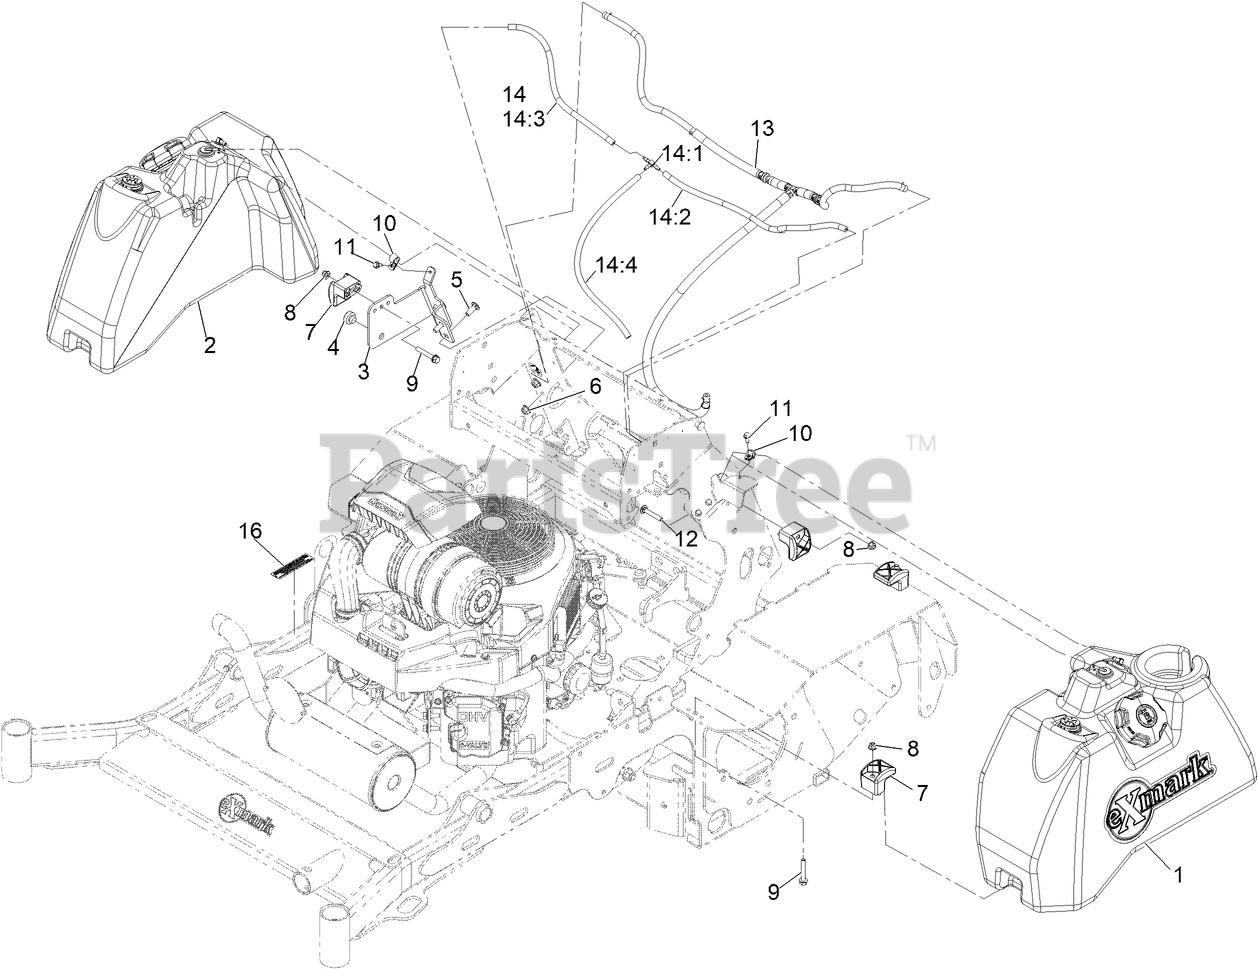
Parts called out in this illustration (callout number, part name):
1	TANK ASM-FUEL, LH
2	TANK ASM-FUEL, RH
3	BRACKET-TANK FUEL
4	BUMPER-RUBBER
5	SCREW-CARR
6	NUT-HF, NI
8	NUT-HF, NI
9	SCREW-HHF
10	CLAMP-R
11	SCREW-HWH
12	BOLT-CARR
13	HOSE ASM-SUPPLY, FUEL
14	HOSE ASM-VENT, FUEL
14:1	FITTING-TEE
14:2	HOSE-FUEL
14:3	HOSE-FUEL
14:4	HOSE-FUEL
16	DECAL-ARRESTOR, SPARK
